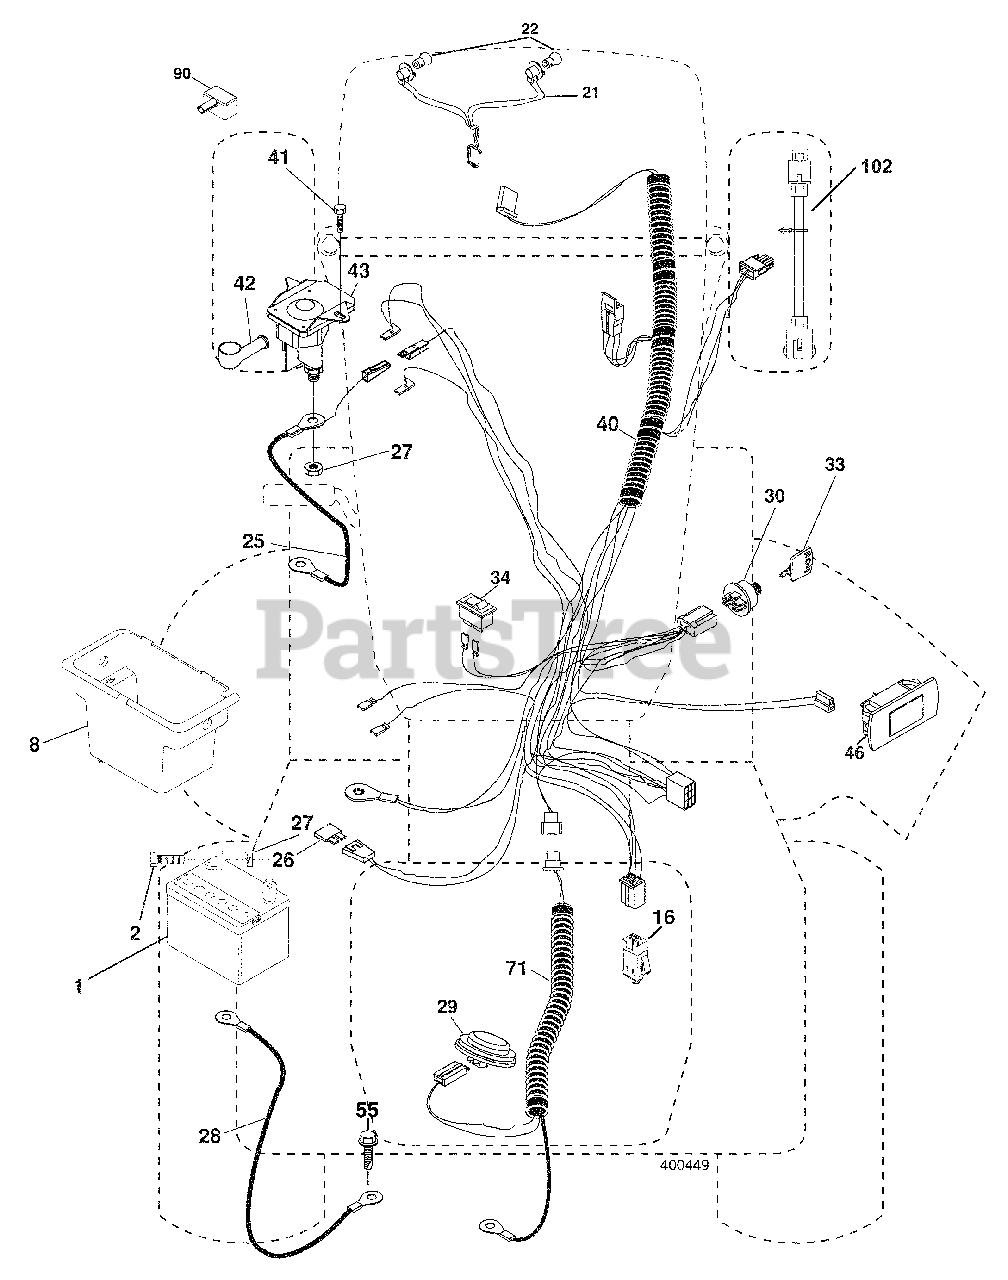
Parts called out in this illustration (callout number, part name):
1	Battery
2	Bolt Hex Head 1/4-20 x 3/4
8	Box Battery
16	Switch Interlock Push-In
21	Harness Socket Light w/4152J
22	Bulb Light
25	Cable Starter
27	Nut Keps Hex 1/4-20 unc
28	Cable, Ground
29	Switch, Seat
30	Switch, Ign
33	Key, Ignition
34	Switch Light / Reset
40	Harness Ign.
41	Screw Thd Cut 1/4-20 x 1/2
42	Cover, Terminal
43	Solenoid
46	Gauge Servicereminder Hrmtr
55	Screw Thdrol 5/16-18 x 3/4 TYTT
71	Harness Ign. Dash
90	Cover Terminal
102	Harness Pigtail
